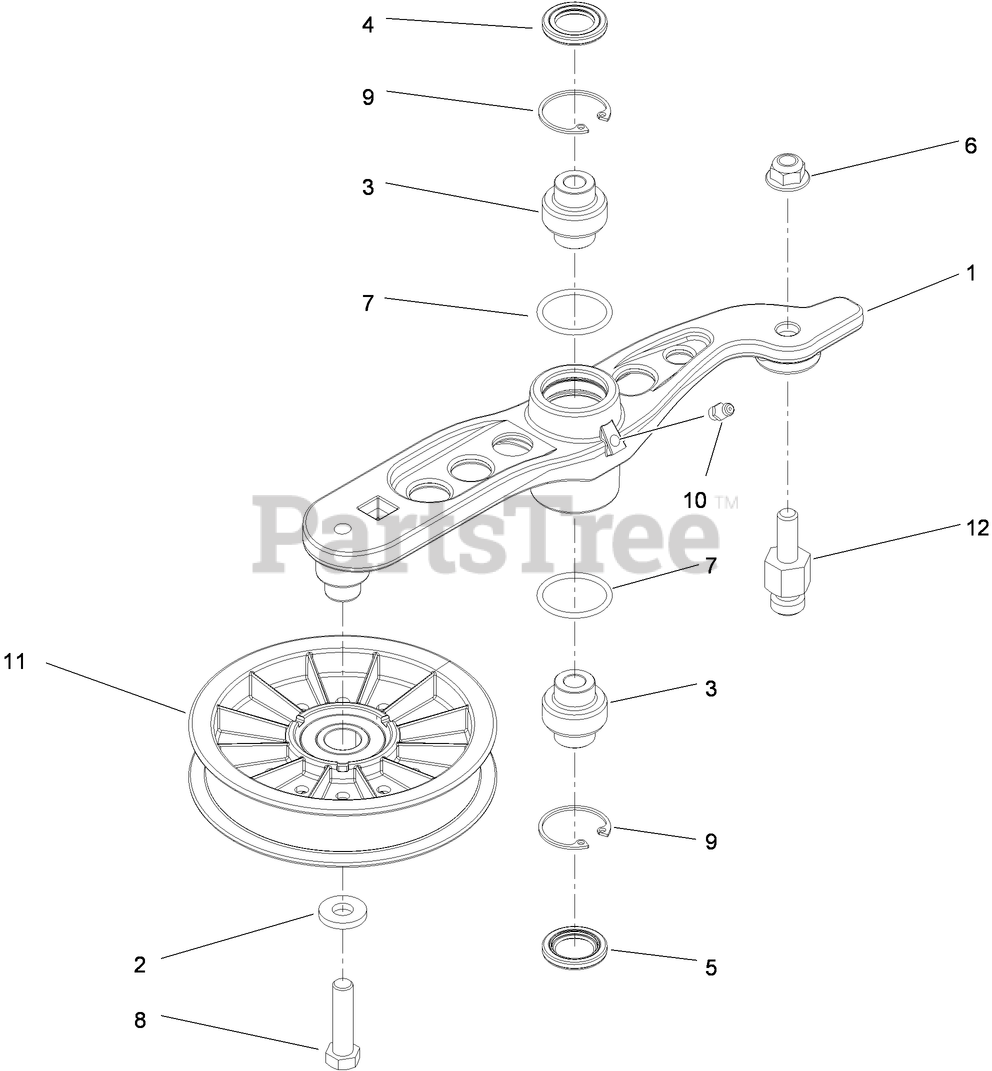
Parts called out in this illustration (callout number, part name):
1	ARM-PUMP, IDLER
2	SPACER
3	BEARING-SPHERICAL
4	SEAL-LIP, DOUBLE
5	SEAL-LIP, SINGLE
6	NUT-FLANGE, NI
7	O-RING
8	SCREW-HH
9	RING-SNAP
10	FITTING-GREASE
11	PULLEY-IDLER
12	PIN-ANCHOR, SPRING
